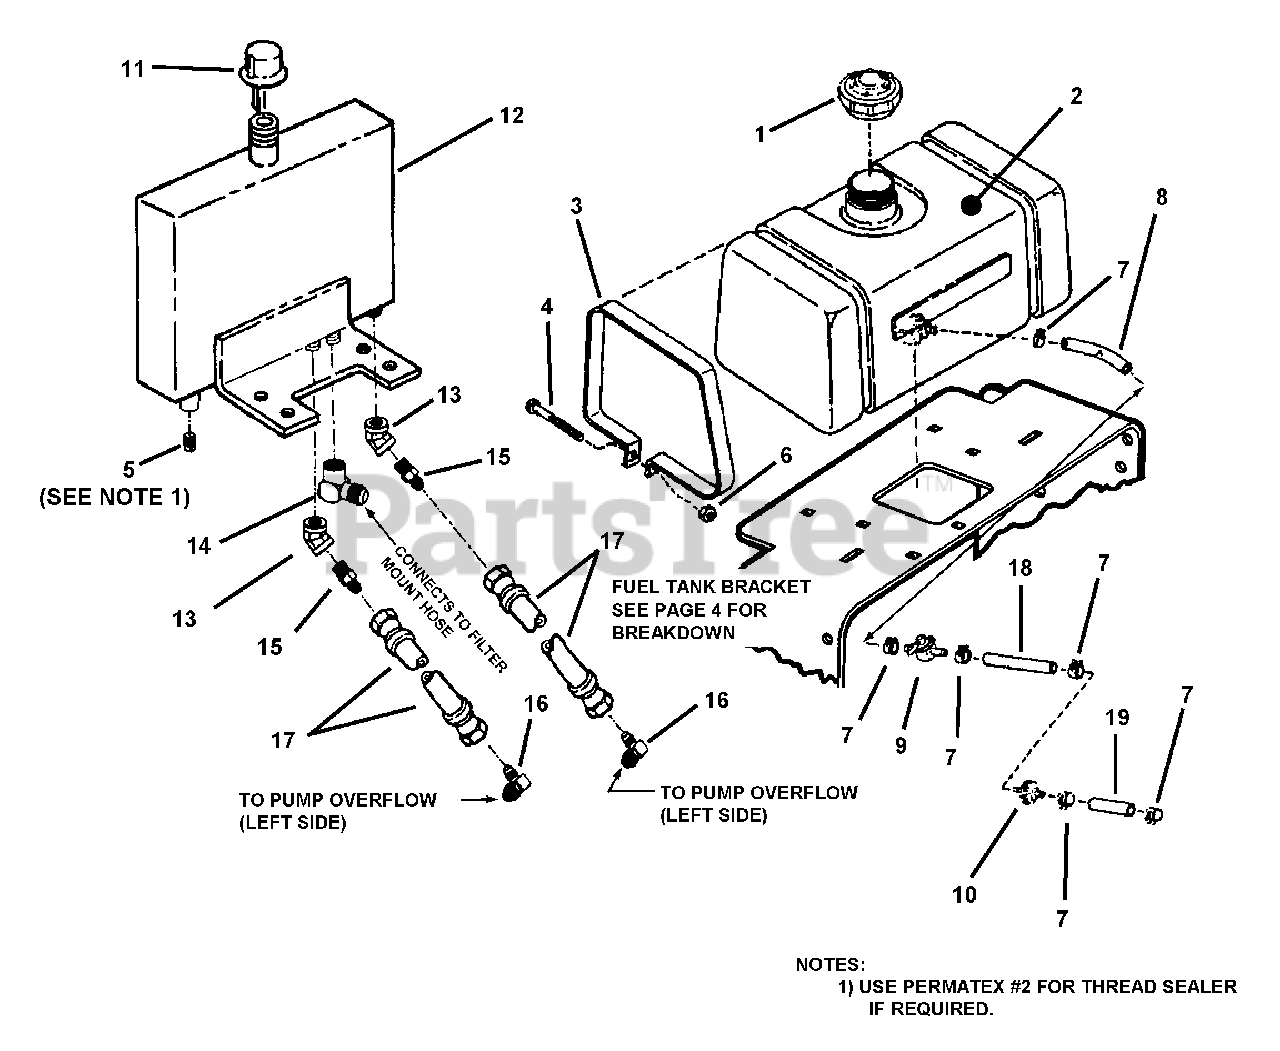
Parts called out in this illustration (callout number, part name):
1	CAP, Fuel
2	TANK, Fuel
3	STRAP, Fuel Tank
4	SCREW, #10-24 x 2" Pan Head
5	PLUG, 1/4 NPTM Pipe
6	NUT, #10-24 Nyloc
7	CLAMP, Fuel Hose
8	HOSE, Fuel, 10" Long
9	VALVE, Fuel Shut-Off
10	FILTER, Fuel In-Line
11	CAP, Hydraulic
12	TANK, Reservoir
13	FITTING, 45 Degree 1/4 FPT Elbow
14	FITTING, 90 Degree
15	FITTING, Straight 1/4
16	FITTING, 90 Degree O-Ring
17	HOSE, 10-1/2" Hydraulic
18	HOSE, Fuel, 10"
19	HOSE, Fuel, 3-1/2"
